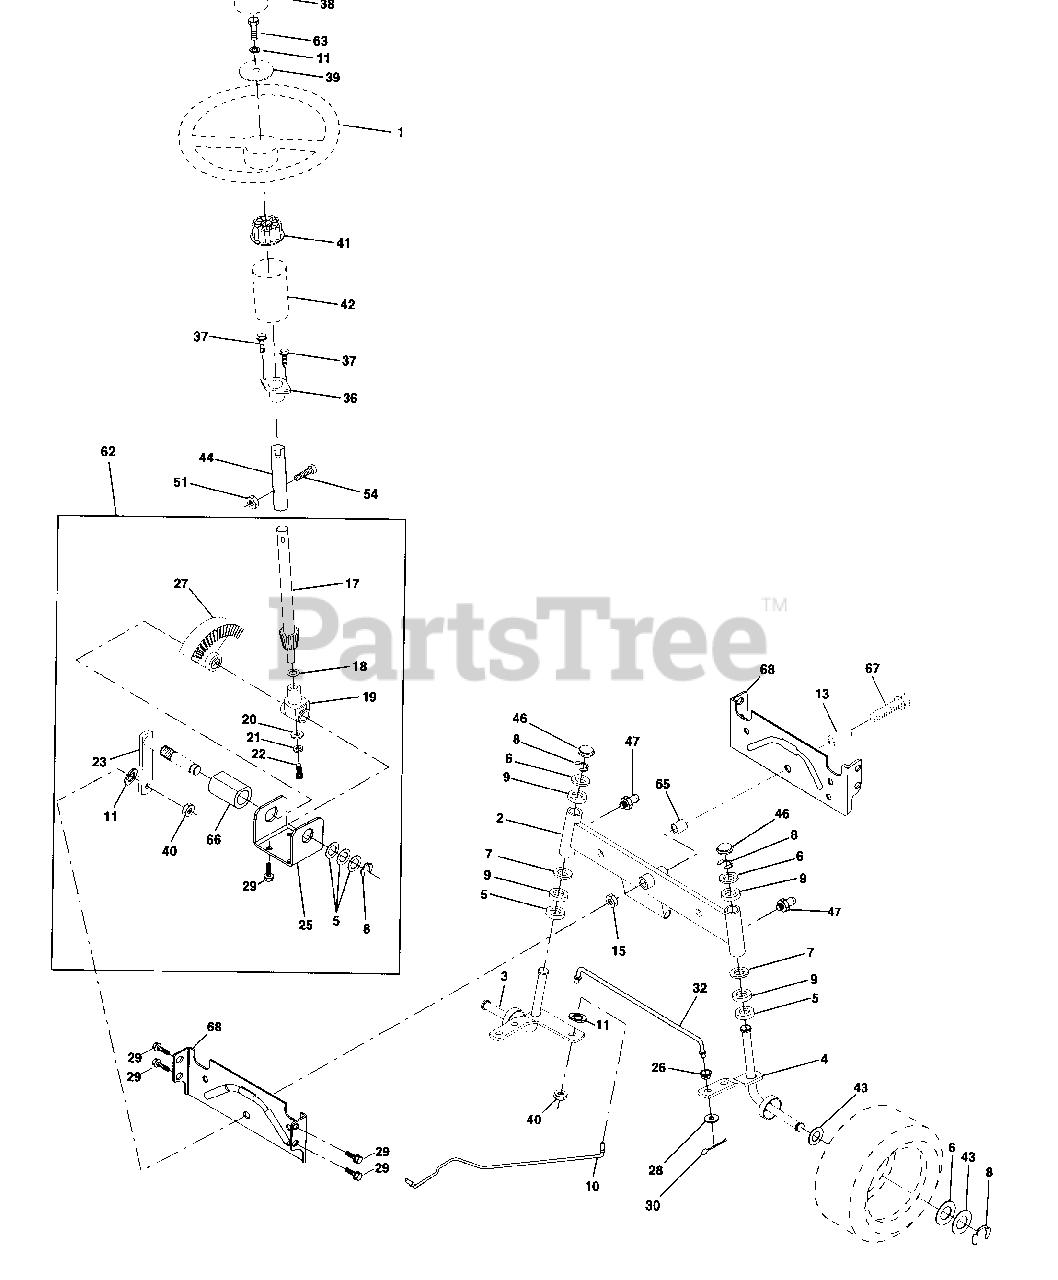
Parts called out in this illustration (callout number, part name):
1	Wheel Steering
2	Axle Asm STMP Dropped STL
3	Spindle Asm LH
4	Spindle Asm RH
5	Bearing Race Thrust Harden
6	Washer 25/32 X 1-5/8 X 16 Ga
7	Washer 27/32 X 1-1/4 X 16 Ga
8	Ring Klip #t5304-75
9	Bearing Col Strg Blk
10	Link Drag Extended Stamp
11	Washer Lock Hvy Hlcl Spr 3/8
13	Bearing Axle STLT/GT
15	Nut Lock Flange 5/8-11 Unc
17	Shaft Asm Strg
18	Washer Thrust 515 x 750 x 033
19	Support Shaft
20	Washer Shim 1/4 X 5/8 X 062
21	Washer Lock Hvy Helical 1/4
22	Screw Cap Sckt Hd Phos & Oil
23	Shaft Asm Pittman
25	Bracket Steering
26	Bushing Link Drag Blk LR
27	Gear Sector
28	Washer 13/32 X 7/8 X 16 Ga
29	Screw Thdrol 3/8-16 x 3/4 Ty-tt
30	Pin Cotter 1/8 X 3/4 Cad
32	Rod Tie Wire Form 19 75 Mech
36	Bushing Strg
38	Insert Cap Strg Wh Au
39	Washer 13/32 X 2-3/8 X 8 Ga
40	Lock nut
41	Adaptor Wheel Strg
42	Boot Steering Shaft
43	Washer 25/32 X 1 1/4 X 16 Ga
44	Extension Steering Shaft LR/LT
46	Cap Spindle Fr Top Blk
47	Fitting Grease
51	Nut Lock Hex w/Ins 5/16-18
54	Bolt Fin Hex 5/16-18 Unc x 1-1/4
62	Kit, Steering Assembly Svc
63	Bolt Fin Hex 3/8-16unc x 1 Gr. 5
65	Spacer Axle
66	Bearing Arm Pittman
67	Bolt, Fin Hex 5/8-11 UNC x 2-3/4
68	Axle, Brace
